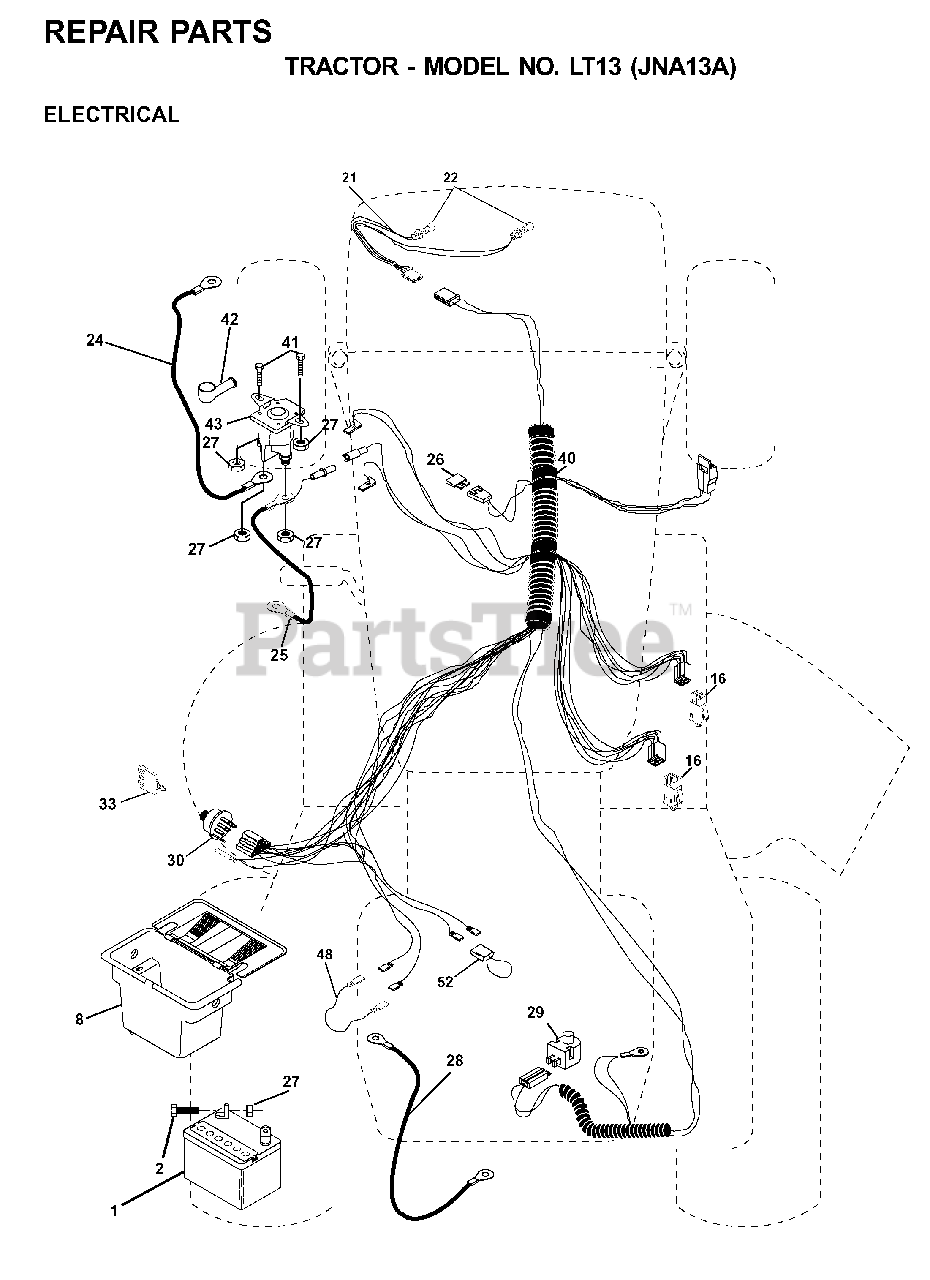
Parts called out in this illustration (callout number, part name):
1	BATTERY 12 VOLT 25 AMP
8	CASE BATTERY MECH HINGE
16	SWITCH INTERLOCK
22	LIGHTBULB
24	BATTERY CABLE GT
25	CABLE BATTERY
26	FUSE 20AMP
27	NUT
28	CABLE T
29	SWITCH SEAT
30	IGNITION SWITCH
33	KEY MLD GEN DELTA
40	CABLE, IGN. HARNESS
42	TERMINAL COVER
43	REPL BY 532 1461-54
52	WIRE PROTECTION LOOP
